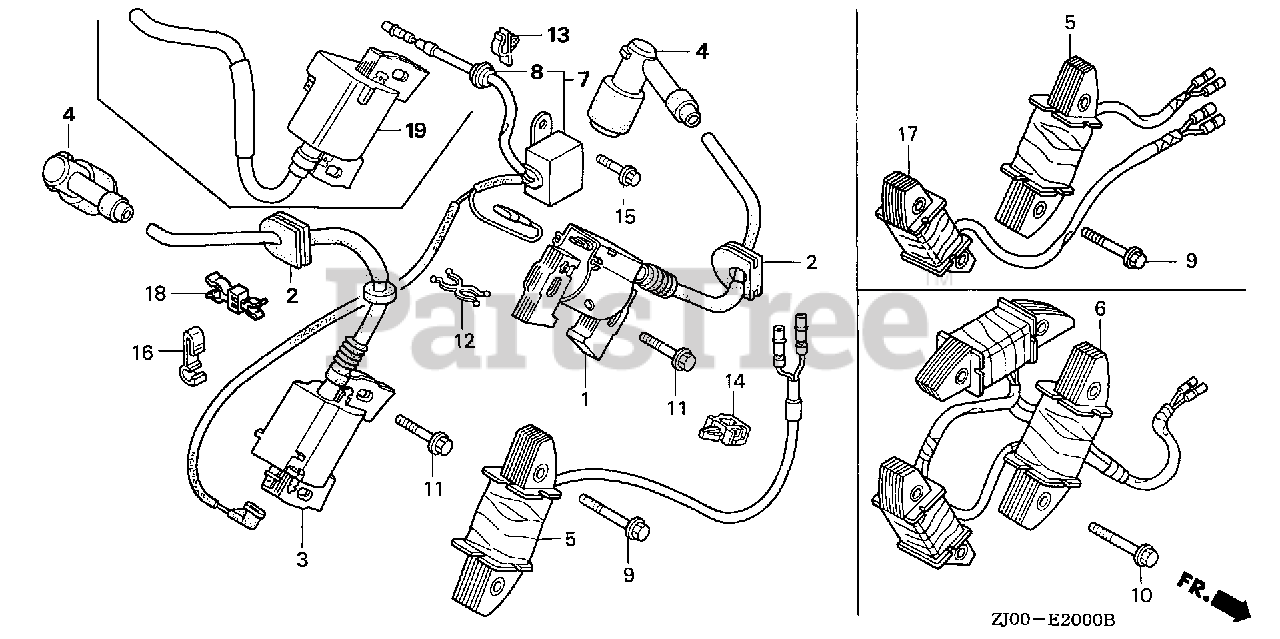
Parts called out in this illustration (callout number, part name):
1	COIL ASSY., IGNITION (200MM) (BLACK)
2	GROMMET, IGNITION WIRE
4	CAP ASSY., NOISE SUPPRESSOR
6	COIL ASSY., CHARGE (12V/20A)
7	DIODE ASSY., ENGINE STOP
8	GROMMET, TOOL
10	BOLT, FLANGE (6X32) (CT200)
11	BOLT, FLANGE (6X32) (CT200)
15	BOLT, FLANGE (6X8)
16	CLAMP, WIRE
19	COIL ASSY., IGNITION (215MM) (GRAY) (R. SIDE)
19	COIL ASSY., IGNITION (215MM) (GRAY)
